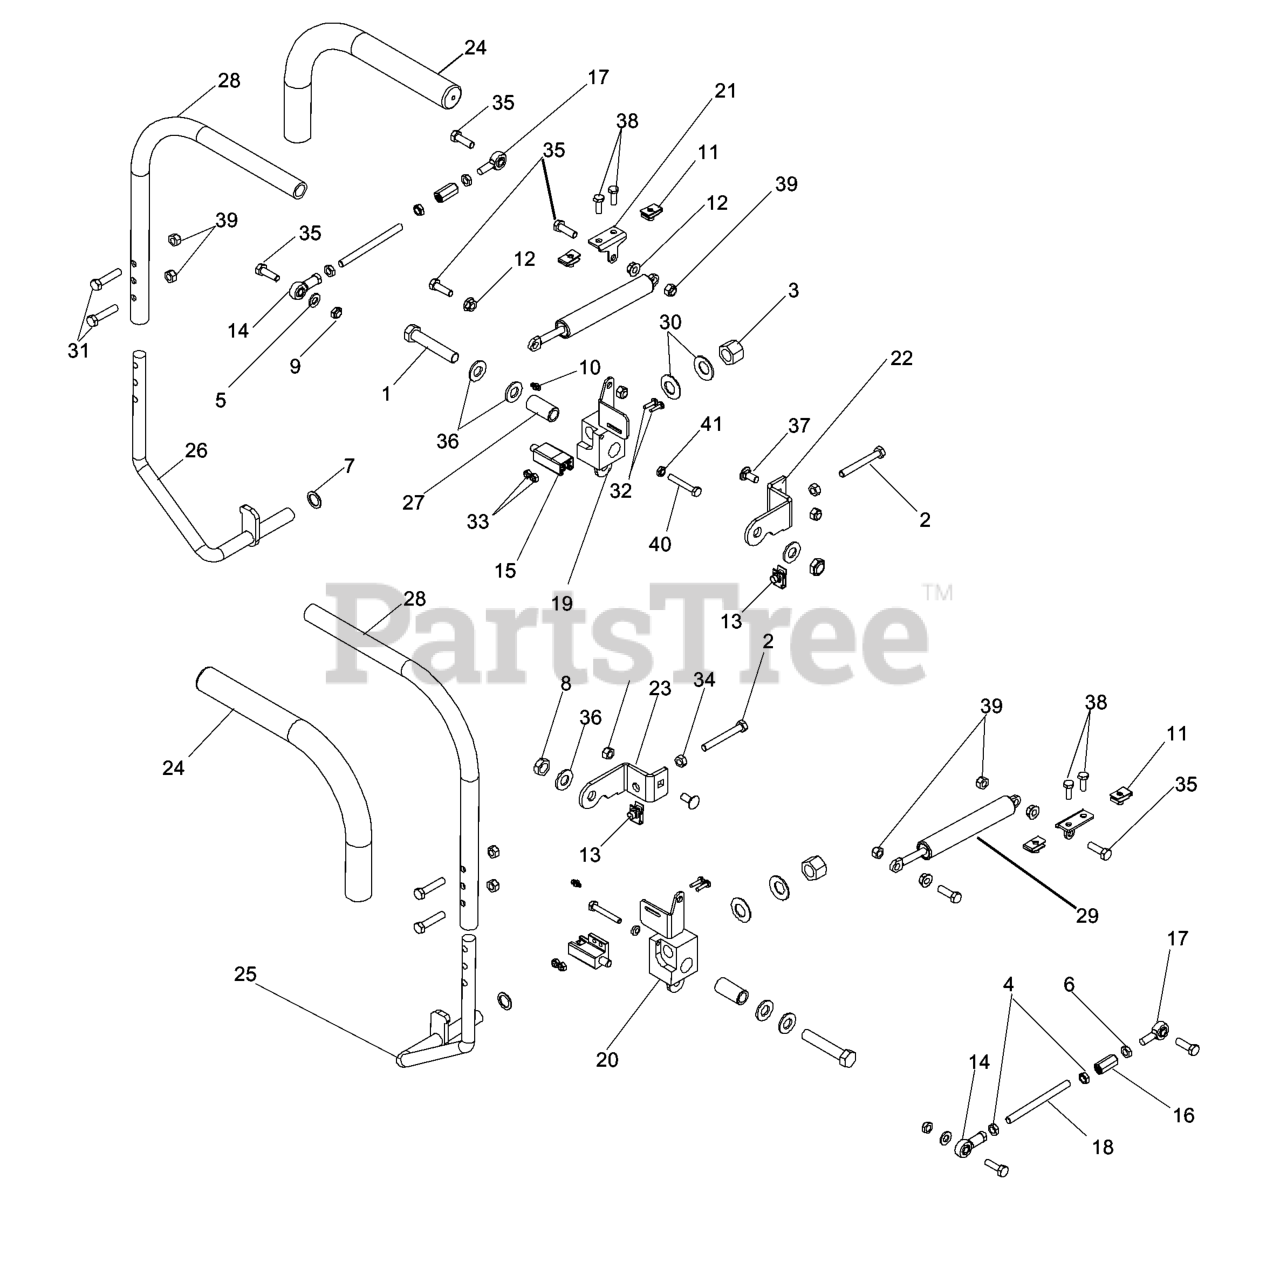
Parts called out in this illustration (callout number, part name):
1	HCS 1/2C X 2 3/4
2	HCS 5/16-18 X 2 1/2 TPBLT
3	NUT 5/8-11 NYLOC
4	NUT 5/16-24 UNF HEX JAM
5	5/16STD FL WASH TYPA
6	NUT 5/16F LEFTHAND
7	WASHER-.626IDX.056TK
8	NUT 1/2-13 HEX JM NYL
9	5/16-18 THIN PROF NY
10	ZERK, 3/16, DRIVE IN
11	1/4C - U TYPE RETAINER
12	5/16-18 FLANGED L-NUT
13	CLIP NUT 5/16-18
14	RH ROD END
15	SWITCH, INTERLOCK
16	ROD END COUPLER
17	ROD.END.LH
19	STEER CONTROL (PLATED)RH
20	STEER CONTROL(PLATED)LH
21	MT. DAMPNER
22	FORWARD STOP RH
23	FORWARD STOP LH
25	LEVER LH (PLATED)
26	LEVER RH (PLATED)
27	BUSHING
28	LEVER UPPER
29	DAMPNER DUAL ACITON #326
30	WASH 5/8 BEVELED DISC SPRING
31	CAPSCREW 5/16 X 1/1/2 HEX HEAD
32	SCREW #10-24 X 5/8
33	NUT 10-24 NYLOC
34	NUT 5/16C HEX
35	HCS 5/16C X 1
36	WASHER 1/2" FLAT
37	BOLT 5/16C X 3/4" CARRIAGE
38	HCS 1/4C X 3/4 HCS
39	NUT 5/16 NYLOC
40	BOLT 1/4C X 1 3/4
41	NUT 1/4-20 JAM
